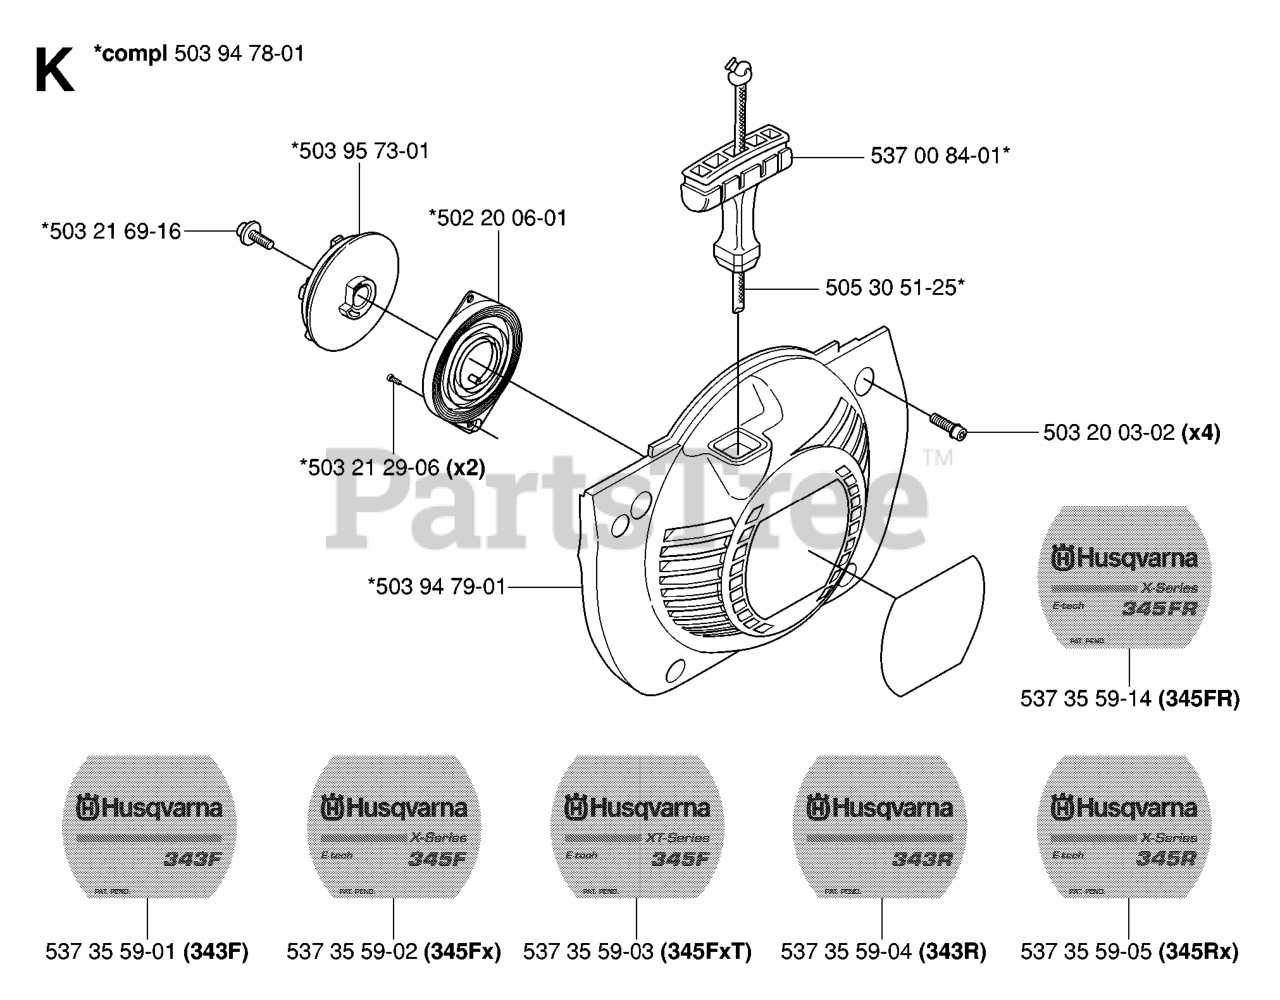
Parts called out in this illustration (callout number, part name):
1	COVER, POWER STEERING
2	SCREW, HEX HEAD, TAPPING
4	RP.DRIVER WHEEL
5	RING, WIRE RETAINER
6	LOBE WHEEL
7	RP.SLIDE.CLUTCH
8	SPRING, CLUTCH SLIDE
9	KEY, SQUARE 1/4 X .875
10	RP.LOBE.AXLE
11	WASHER TRUST 1"
12	YOKE, STEERING
13	BRACKET.STEER.PNT.BLACK
14	Screw 5/16-18 x 1/2 Hex, Self Tapping 5/16-18 x 1/2
15	BRKT.STEER.PIVOT.RH
16	BELLCRANK.STEER
17	PIN, STEERING BELLCRANK
18	SCREW 1/4X20
19	LINK.STEER.YOKE
20	RETAINER CLIP
21	RETAINER CLIP PM
22	SPRING LATCH
23	PIN, STEERING LEVER
24	BRACKET.STEER.PIVOT.LH.YZ
